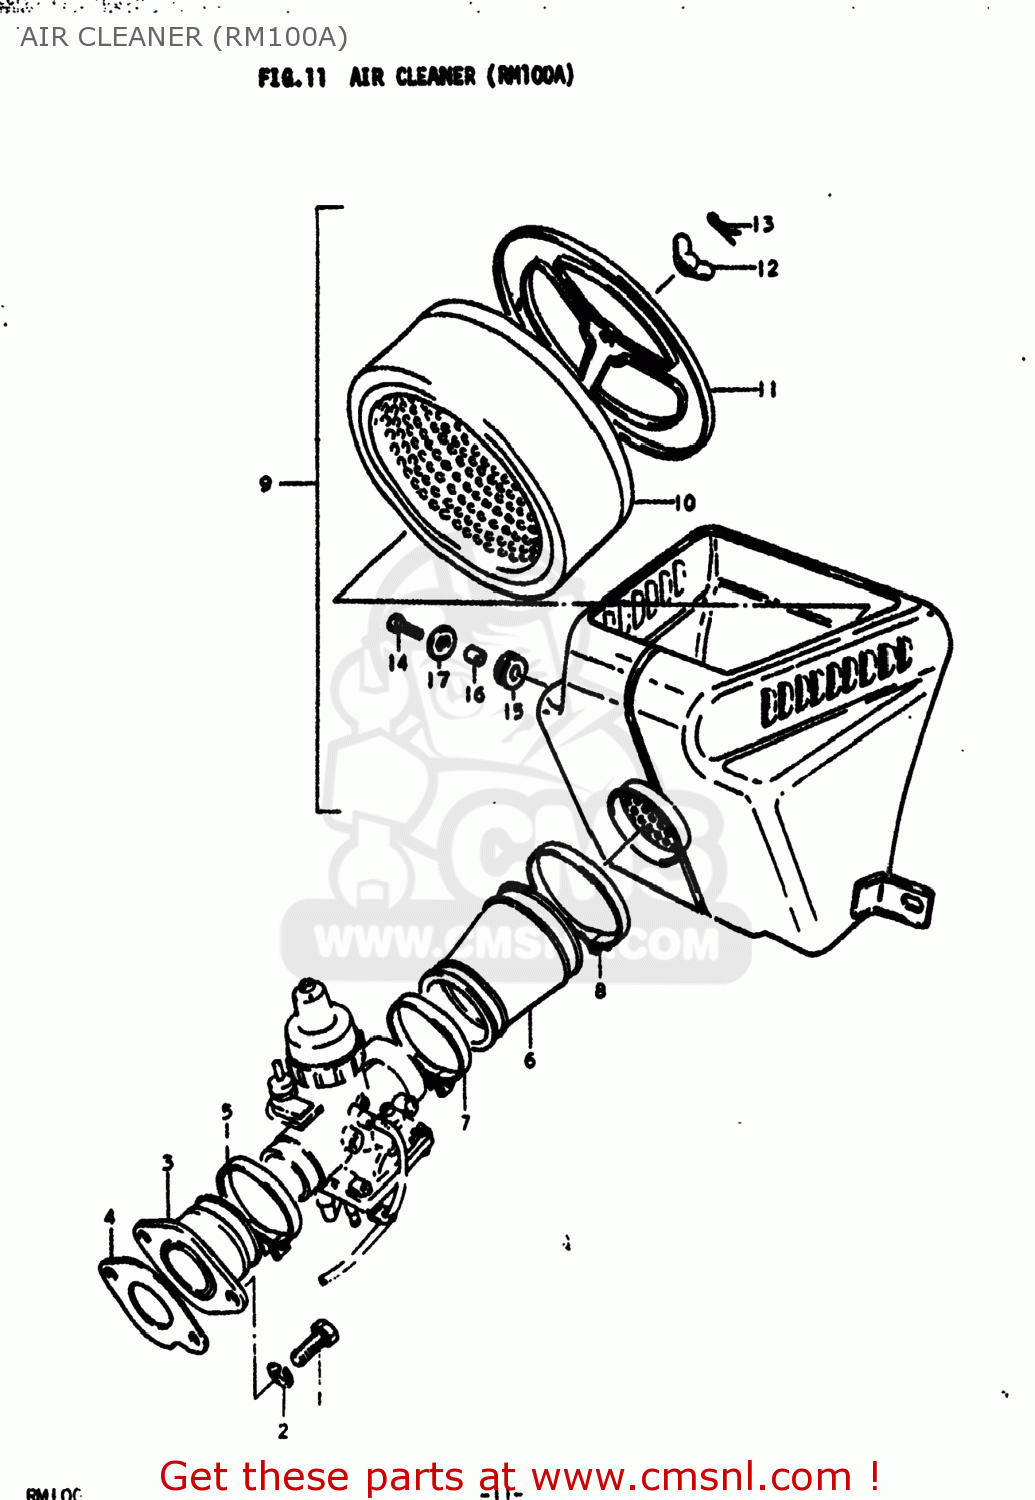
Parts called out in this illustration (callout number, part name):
1	BOLT
2	LOCK WASHER
3	PIPE,INTAKE
4	GASKET,CARBURETOR (MCA)
5	CLAMP
6	TUBE,AIR CLEANER OUTLET
7	CLAMP
8	CLAMP
9	CLEANER ASSEMBLY,AIR
10	FILTER,AIR CLEANER
12	NUT
14	BOLT
15	CUSHION
16	SPACER (7X9X7)
17	WASHER (6.5X20X1.2)
